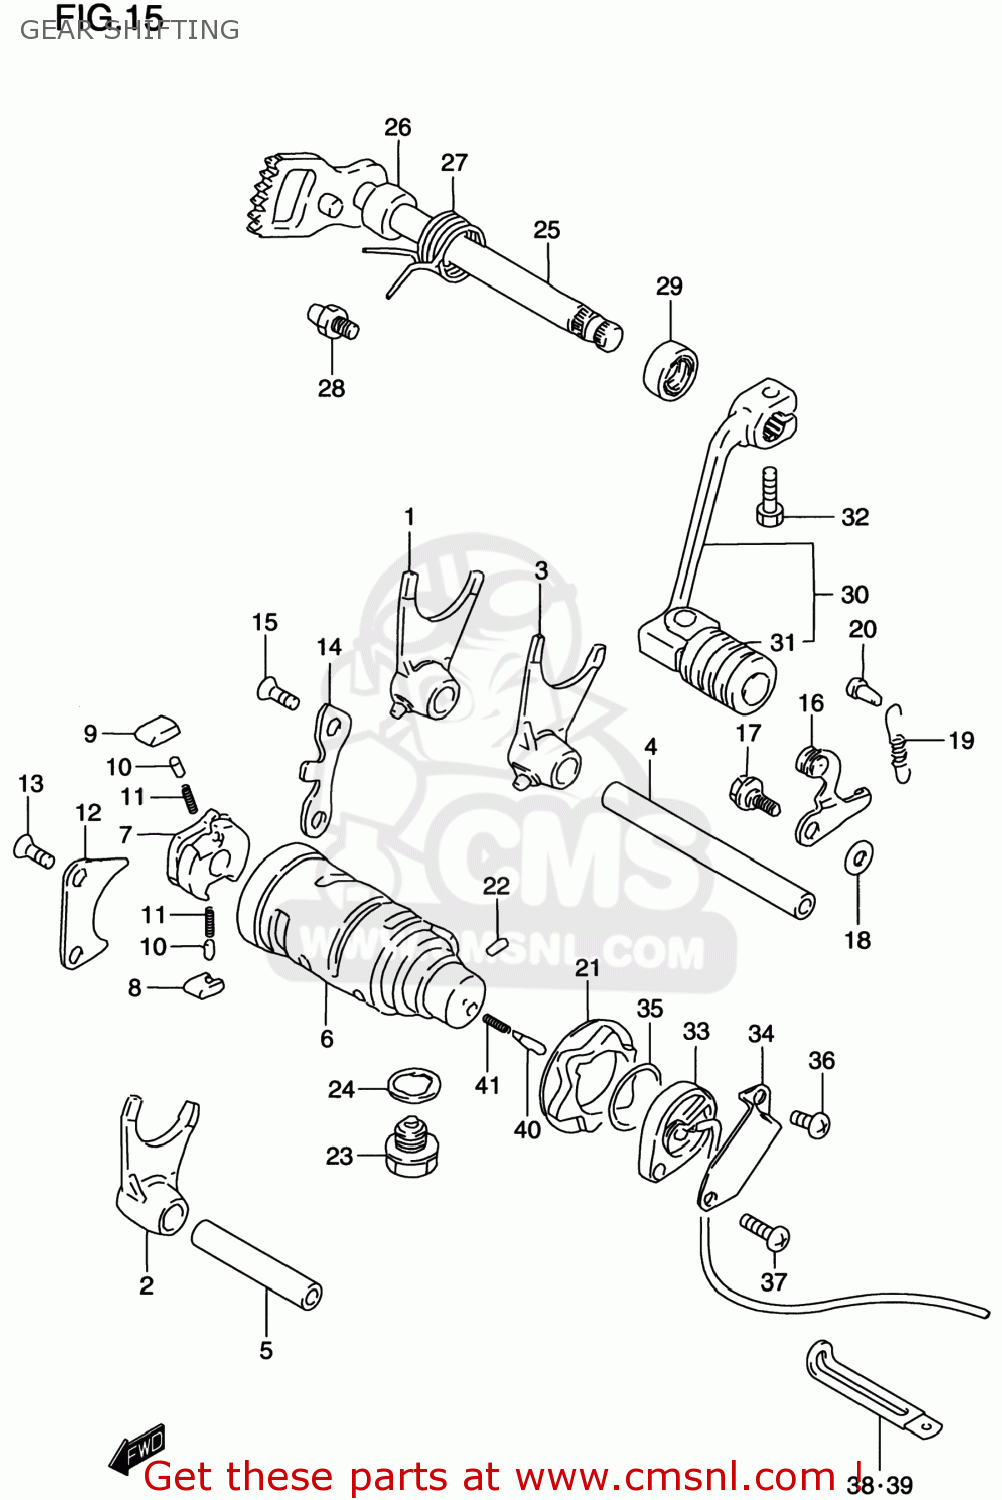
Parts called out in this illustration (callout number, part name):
1	FORK,GEAR SHIFT NO.1
2	FORK,GEAR SHIFT NO.2
3	FORK,GEAR SHIFT NO.3
4	SHAFT,GEAR SHIFT FORK
5	SHAFT,GEAR SHIFT FORK
6	CAM,GEAR SHIFT
7	GEAR,GEARSHIFT CAM DRIVE
8	PAWL,GEAR SHIFT NO.1
9	PAWL,GEAR SHIFT NO.2
10	PIN(5X8)
11	SPRING
12	LIFTER,GEAR SHIFT POLE
13	SCREW
14	GUIDE,GEAR SHIFT CAM
15	SCREW
16	STOPPER COMP,GEAR SHIFT
17	BOLT(6X14.6)
18	WASHER
19	SPRING
20	RIVET
21	PLATE,GEAR SHIFT CAM STOPPER
22	PIN
23	PLUG (14X12)
24	GASKET(13.8X18.8X4.8) (NAS)
25	SHAFT,GEAR SHIFT
26	SPACER(12X20X15.3)
27	SPRING
28	STOPPER,GEAR SHIFT CAM
29	OIL SEAL
30	LEVER ASSY,GEAR SHIFT
31	RUBBER,GEAR SHIFT PEDAL
32	BOLT
33	BASE ASSY,NEUTRAL SW TERMINAL
34	PROTECTOR,GEAR SHIFT SW
35	O RING(D:2.4,ID:21.8)
36	SCREW
37	SCREW
38	CLAMP(L:45)
39	CLAMP(L:45)
40	PIN(5X15.5)
41	SPRING
